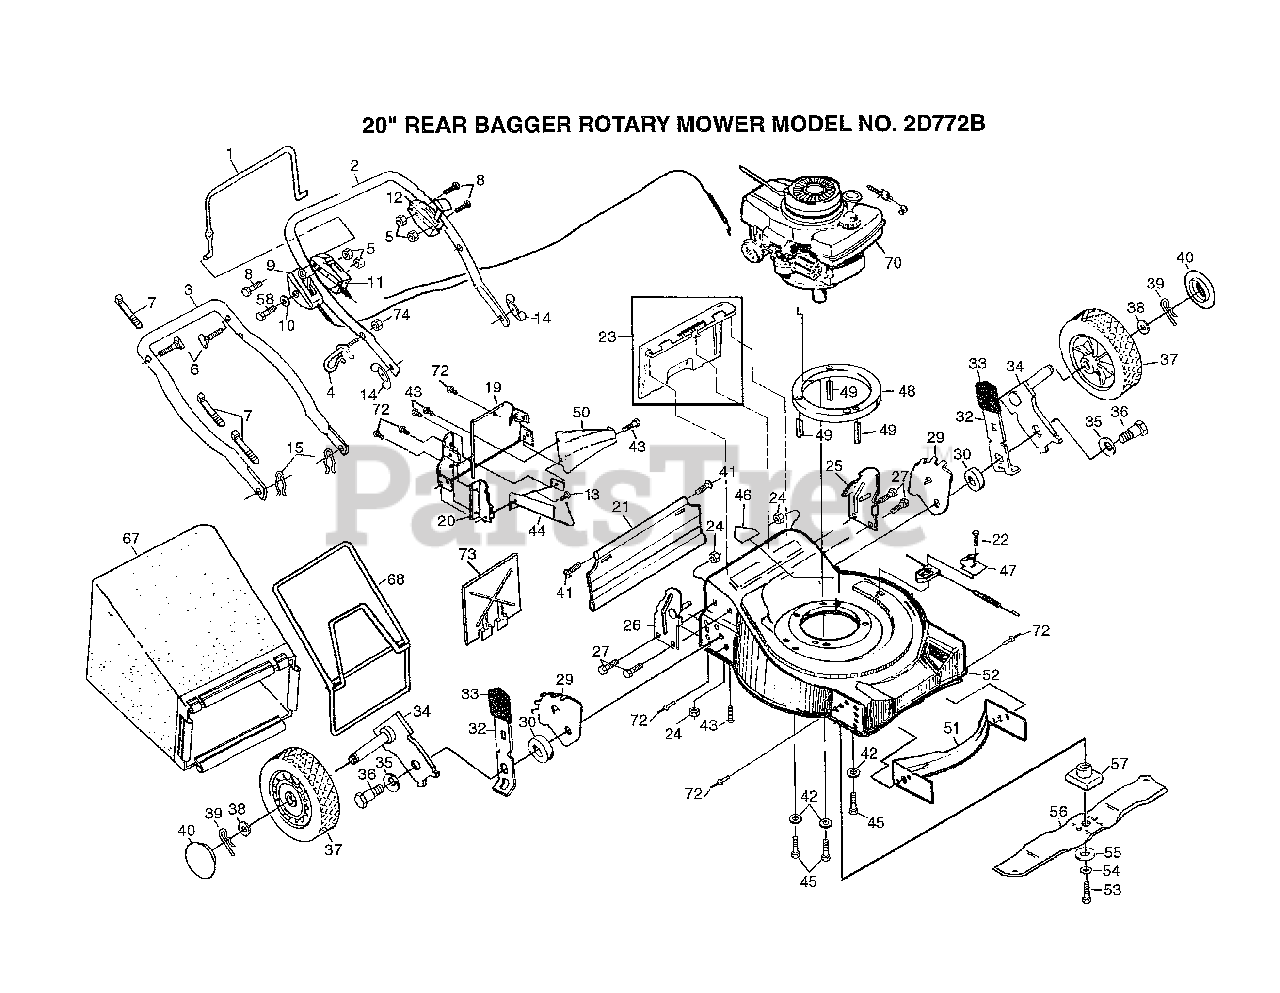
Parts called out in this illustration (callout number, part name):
1	CONTROL BAR
4	ROPE GUIDE
6	BOLT.HANDLE.LM
10	WASHER PM
11	CABLE MZR E/S
12	DRIVE CONTROL
13	SCREW PM
14	"NUT,WING PM"
15	HAIRPIN COTTER
19	"PLATE.BACK.20"""
21	SKIRT.PUSH.20RD
22	"SCREW, HEX PM"
23	"KIT, REAR DOOR PM"
24	LOCKNUT PM
27	SCREW
29	BRACKET.ADJ.9POS.
32	SPRING SELECTOR
33	KNOB PM
34	AXLE ARM
35	"WASHER, BELLEVIL."
36	BOLT SHLD 3/8-16
37	WHEEL&TIRE ASSY
38	WASHER
39	RETAINER CLIP PM
40	HUB CAP
41	HINGE SCREW
43	SCREW
44	DISCHARGE GUARD
45	SCREW
46	DECAL HYT
47	BRKT DRV COV
48	ENGINE SPACER
50	REAR BAFFLE
52	KIT.HSG.20RD.FWBD
53	SCREW
54	LOCKWASHER
55	"WASHER,HARDEN"
57	ADAPTOR.BLADE.LM
67	GRASS BAG
68	CATCHER FRAME
72	BLIND RIVET
73	MULCHER PLATE
74	NUT
